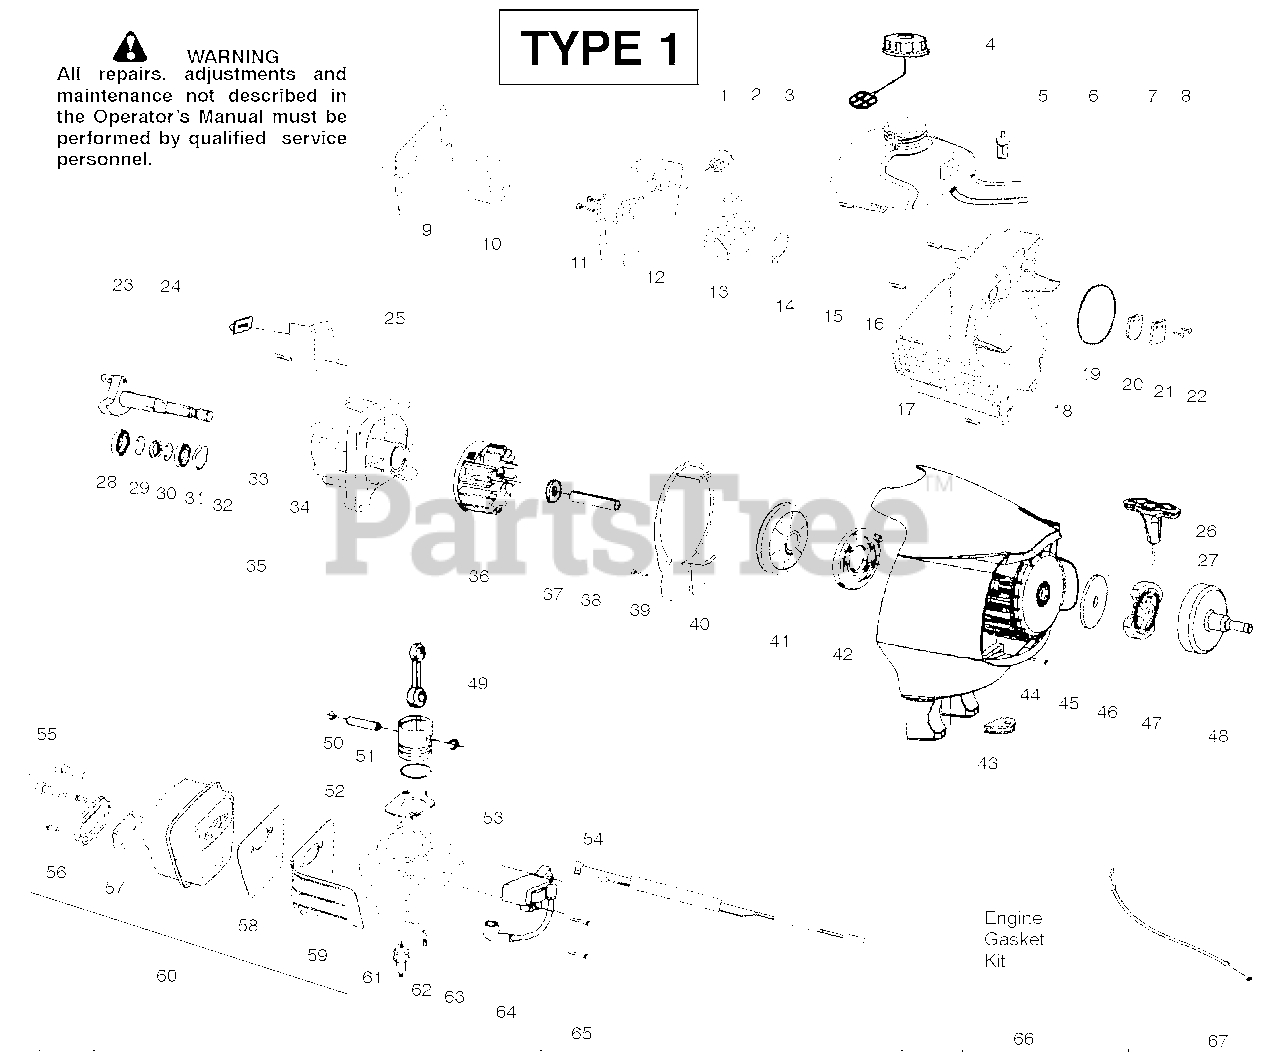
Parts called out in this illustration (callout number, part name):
2	Kit-Choke Lever
4	Cap-Fuel w/ret.
5	Assy-Fuel pickup
6	Kit-Fuel line
7	Kit-Fuel/Purge line
9	Cover-Air box
13	Kit-Carb assy. (C1U-W32)
14	Seal-Carb.(kit)
15	Assy-Fuel Tank
16	Screw-Crankcase
18	Assy-Rear Shroud
19	O-ring-Shroud (kit)
22	Screw-Reed stop
23	Screw-Retainer
24	Isolator-Tank
26	Handle-Starter
27	Kit-Rope
28	Bearing-Inner
31	Bearing-Outer
32	Ret.-Crankshaft
33	Assy-Crankshaft
34	Assy-Crankcase
35	Assy-C'case/C'shaft
36	Assy-Flywheel
37	Washer
40	Plate-Baffle
42	Spring-Starter
44	Screw-F/hsg.
45	Assy-Fan Housing
46	Washer-Clutch
48	Assy-Drum/Adapter
49	Assy-Conn. Rod
50	Ret.-Piston pin
52	Kit-Piston
53	Gasket-Cylinder(kit)
54	Assy-Leadwire
55	Bolt-Muffler 1/4"-20
56	Screw
57	Kit-Spark Arrestor
58	Gasket-Muffler (kit)
61	Cylinder
62	Plug-Spark(RCJ-6Y)
63	Bolt-Cyl. 1/4"-20
64	Module-Ignition
66	Kit-Gasket/Seal
67	Assy-Throttle cable
